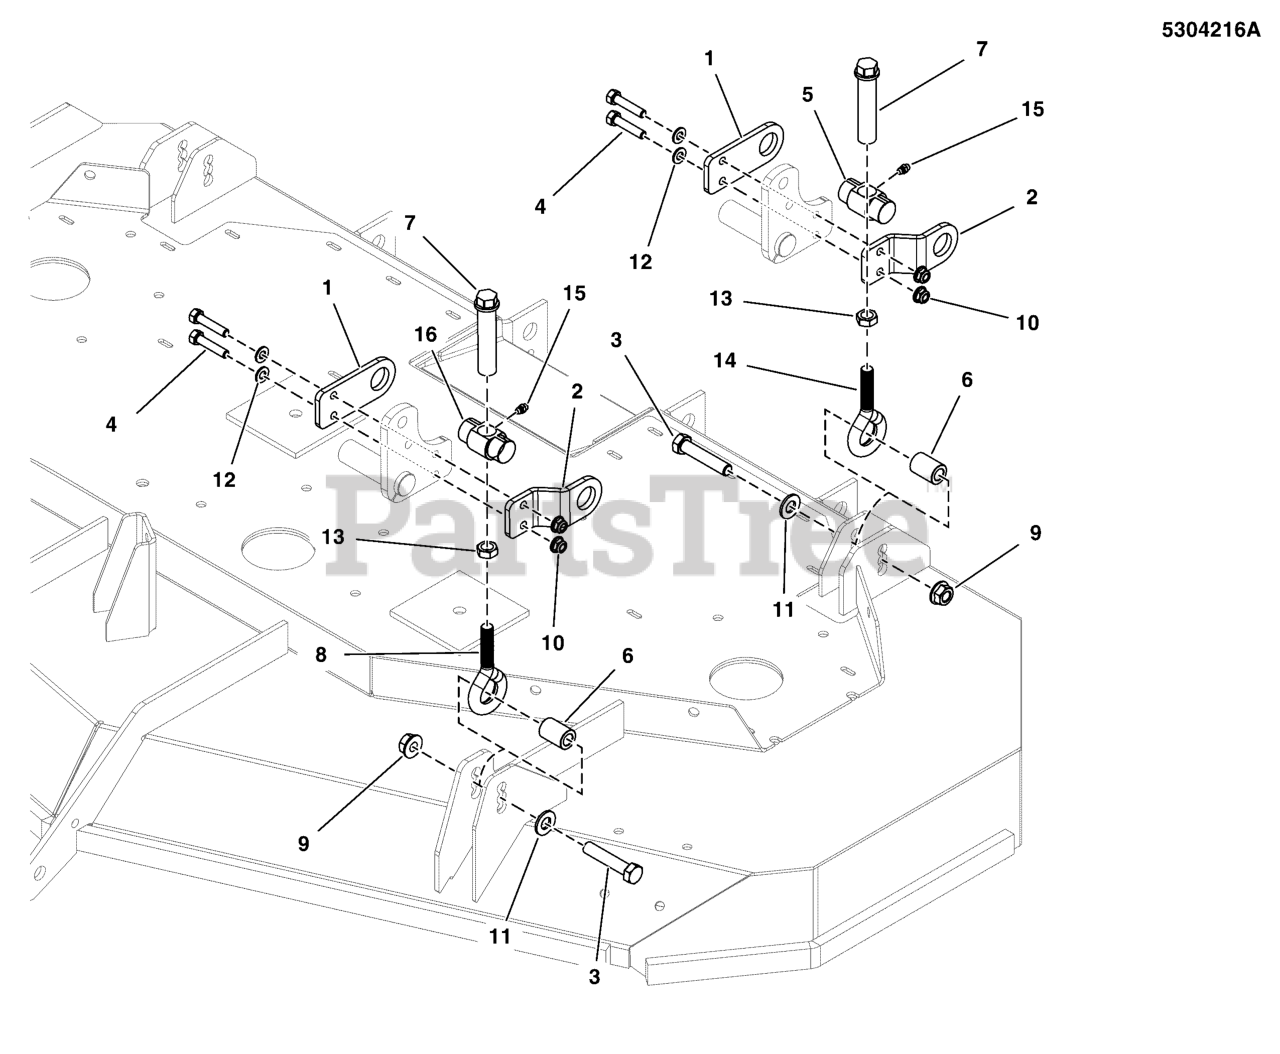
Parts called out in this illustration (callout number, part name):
1	BRACKET, INNER TRUNION MNT - BLK
2	BRACKET, OUTER TRUNION MNT - BLK
3	BOLT, 1/2-13 X 2-1/2" GD5 CZ
4	BOLT, 3/8-16 X 1-1/2" GD5 CZ
5	PIVOT, DECK LIFT TRUNION, GREASABLE
6	SPACER, .52 X .87 X 1.25, CZ
7	ADJUSTER, HEIGHT
8	EYE BOLT, 1/2-20X6", 2.5"THRD,
9	NUT, Hex Flange, Nylock, 1/2-13
10	NUT, 3/8 - 16 HEX NYLOCK FLANGE
11	WASHER, 1/2 SAE
12	WASHER, 3/8 SAE
13	NUT, 1/2-20 Hex Jam
14	EYE BOLT, 1/2-20 X 4.25,1.88THRD,1EYE,CZ
15	GREASE FITTING, 1/4-28 Straight
16	PIVOT, DECK LIFT, TRUNION, HT, BZ
